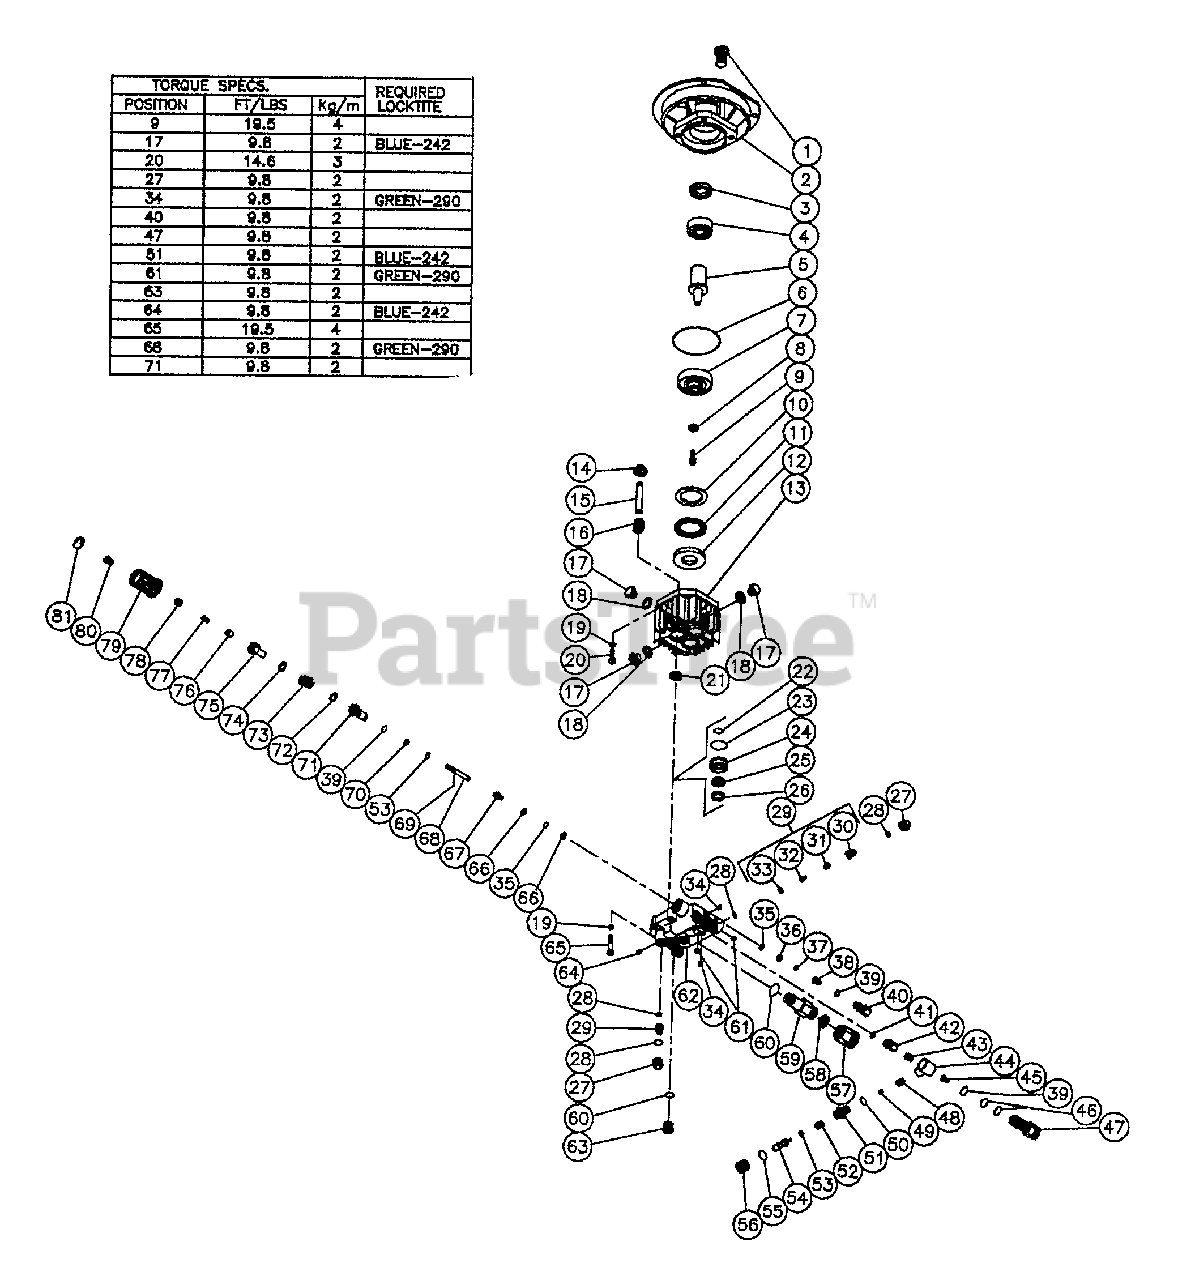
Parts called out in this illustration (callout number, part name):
3	Oil Seal
7	Wobble Plate
10	Bearing Disc
12	Bearing Disc
13	Pump Housing
14	Piston Spring Retainer
16	Piston Spring
17	Oil Drain Plug
19	Lockwasher
21	Oil Seal (See 07575-06)
22	O-ring (See 07575-16)
23	O-ring (See 07575-16)
24	V-Packing Retainer
25	V-Packing (See 07575-16)
26	Pack Ring (See 07575-16)
27	Valve Plug
29	Valve Complete (See 07575-17)
30	Valve Cage (See 07575-17)
31	Valve Spring (See 07575-17)
32	Valve Plate (See 07575-17)
33	Valve Seat (See 07575-17)
36	Valve Seat
38	Valve Spring
42	No Return Valve
44	Injector Body
45	Injector Nozzle
47	Pressure Outlet
48	Spring (See 07575-20)
49	Ball (See 07575-20)
50	O-ring (See 07575-20)
51	Injector Nipple
52	Injector Spring
53	O-ring (See 0792539)
54	Injector Piston
55	Flexible Ring
56	Injector Regulation Knob
57	Garden Hose Connection
59	Inlet Connector
62	Manifold
63	Manifold Plug
66	Back-up Ring
67	Piston By-pass (See 07575-19)
68	Pressure Regulator (See 07575-19)
69	Roll Pin
70	Back-up Ring (See 07575-19)
71	Plug (See 07575-19)
73	Pressure Regulation Spring
75	Pressure Regulation Screw
76	Screw Support
78	Internal Screw
79	Pressure Regulation Knob
